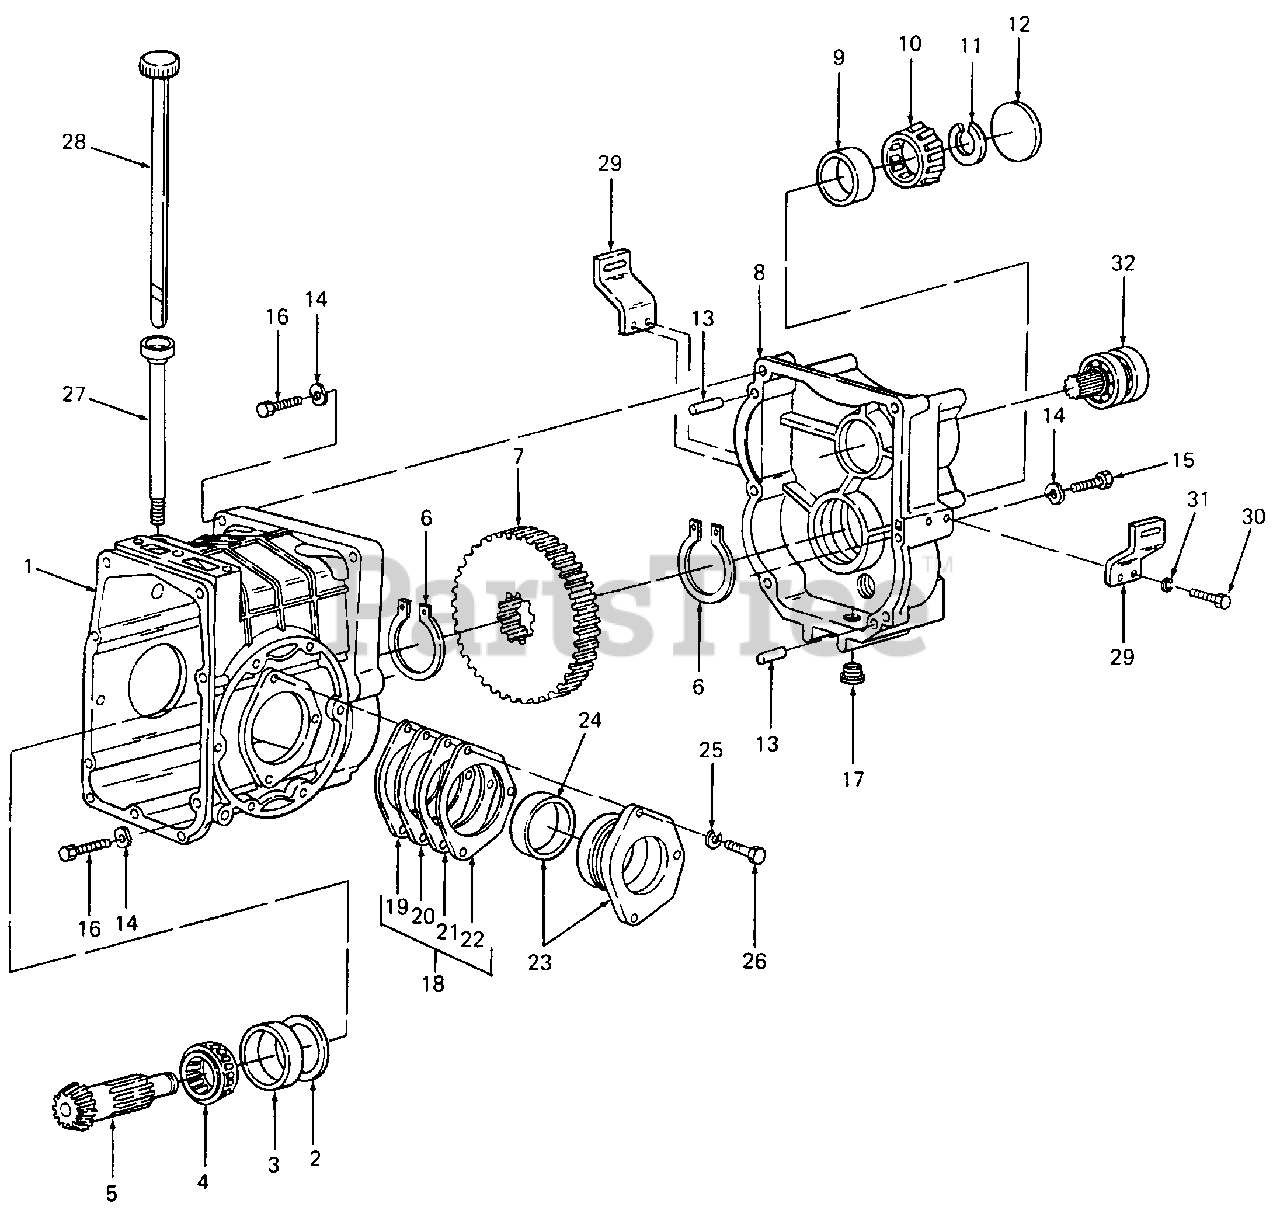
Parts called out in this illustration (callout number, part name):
1	Housing Assy, Rear Transaxle
2	Shim, Rear Bearing Cup, .004 Thk
3	Cup, Roller Bearing
4	Cone, Roller Bearing
5	Shaft, Bevel Pinion
6	Ring, Retaining, 1.312 Dia
7	Gear, Reduction - 71T
8	Adapter Housing Assy
9	Cup, Roller Bearing
10	Cone, Roller Bearing
11	Retainer, Front Bearing, .125 Thk
12	Plug, Expansion, 2.12 OD
13	Pin, Dowel, 3/8 Dia x 5/8 Lg
14	Washer, Spring, .445 x .75 x .017 Thk
15	Screw, Hex Cap, 7/16-14 x 2.75 Lg GR5
16	Screw, Hex Cap, 7/16-14 x 1.75 Lg GR5
17	Plug, Drain
18	Shim, Package
19	Shim, Bearing Retainer, .004 Thk
20	Shim, Bearing Retainer, .007 Thk
21	Shim, Bearing Retainer, .014 Thk
22	Shim, Bearing Retainer, .028 Thk
23	Retainer Assy, Bearing
24	Cup, Roller Bearing
25	Washer, Lock, 3/8
26	Bolt, Hex Patch, 3/8-16 x 1.0 Lg GR5
27	Tube, Dipstick
28	Blade Assy, Dipstick
30	Screw, Hex Cap, 3/8-16 x 1.0 Lg GR8
31	Washer, Lock, 3/8
32	Pinion Assy, Input
